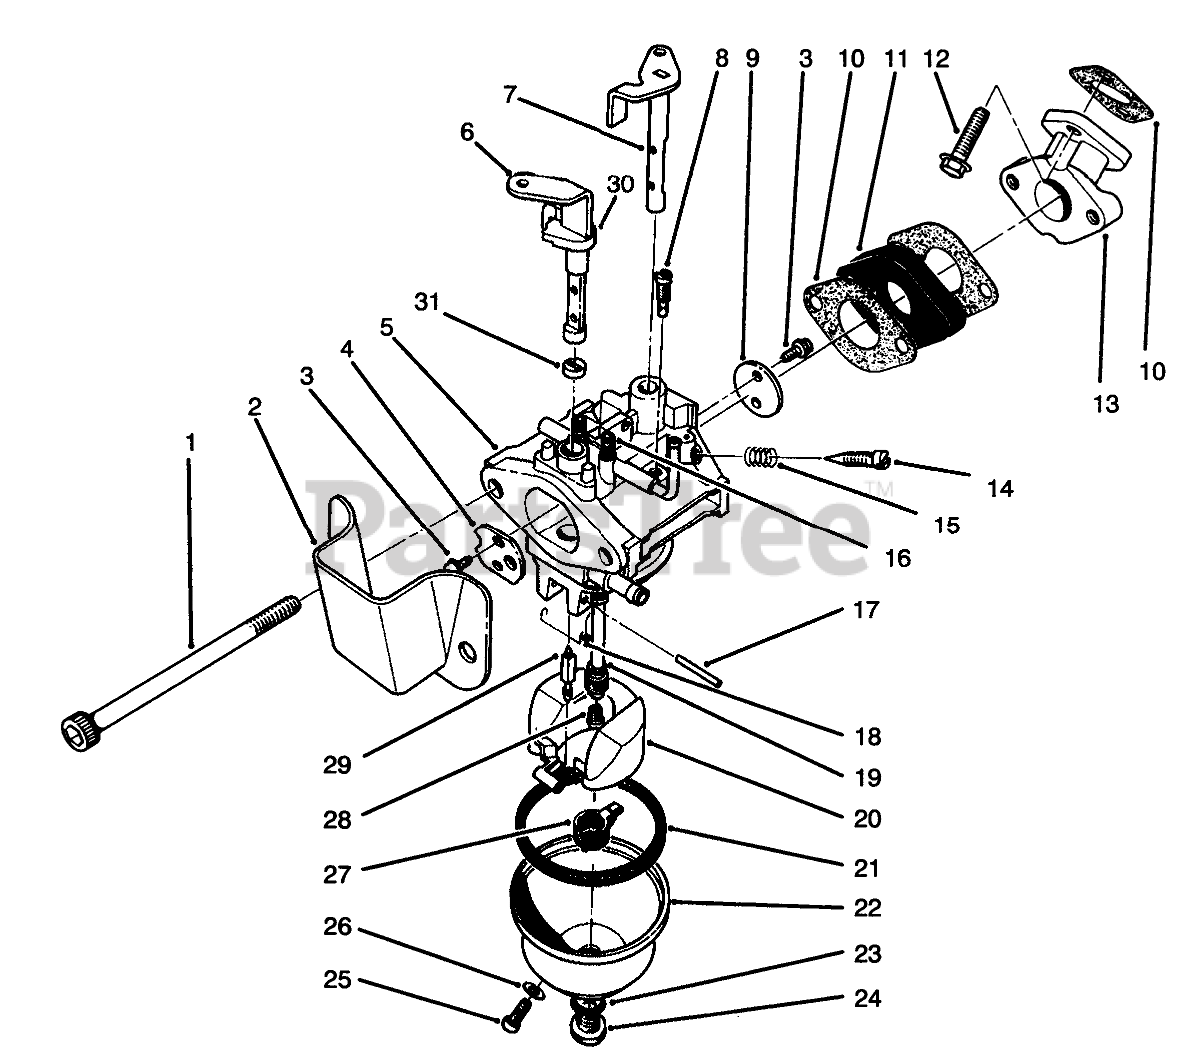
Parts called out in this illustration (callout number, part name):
2	SPIT CUP
3	Screw
4	VALVE
5	Body-Carburetor
6	Shaft-Choke (Incl. Ref. #30 & 31)
7	SHAFT
9	VALVE
10	Gasket-Carburetor
11	CARB INSULATOR
13	MANIFOLD
14	ADJUSTER
15	SPRING-PILOT SCREW
16	SPRING
17	PIN-HINGE
18	TORSION SPRING
19	MAIN NOZZLE
20	FLOAT
21	FLOAT BOWL GASKET
23	GASKET
24	SCREW
25	SCREW
26	GASKET
27	SPACER
28	MAIN JET
29	NEEDLE
30	UPPER CHOKE RING
31	LOWER CHOKE RING
